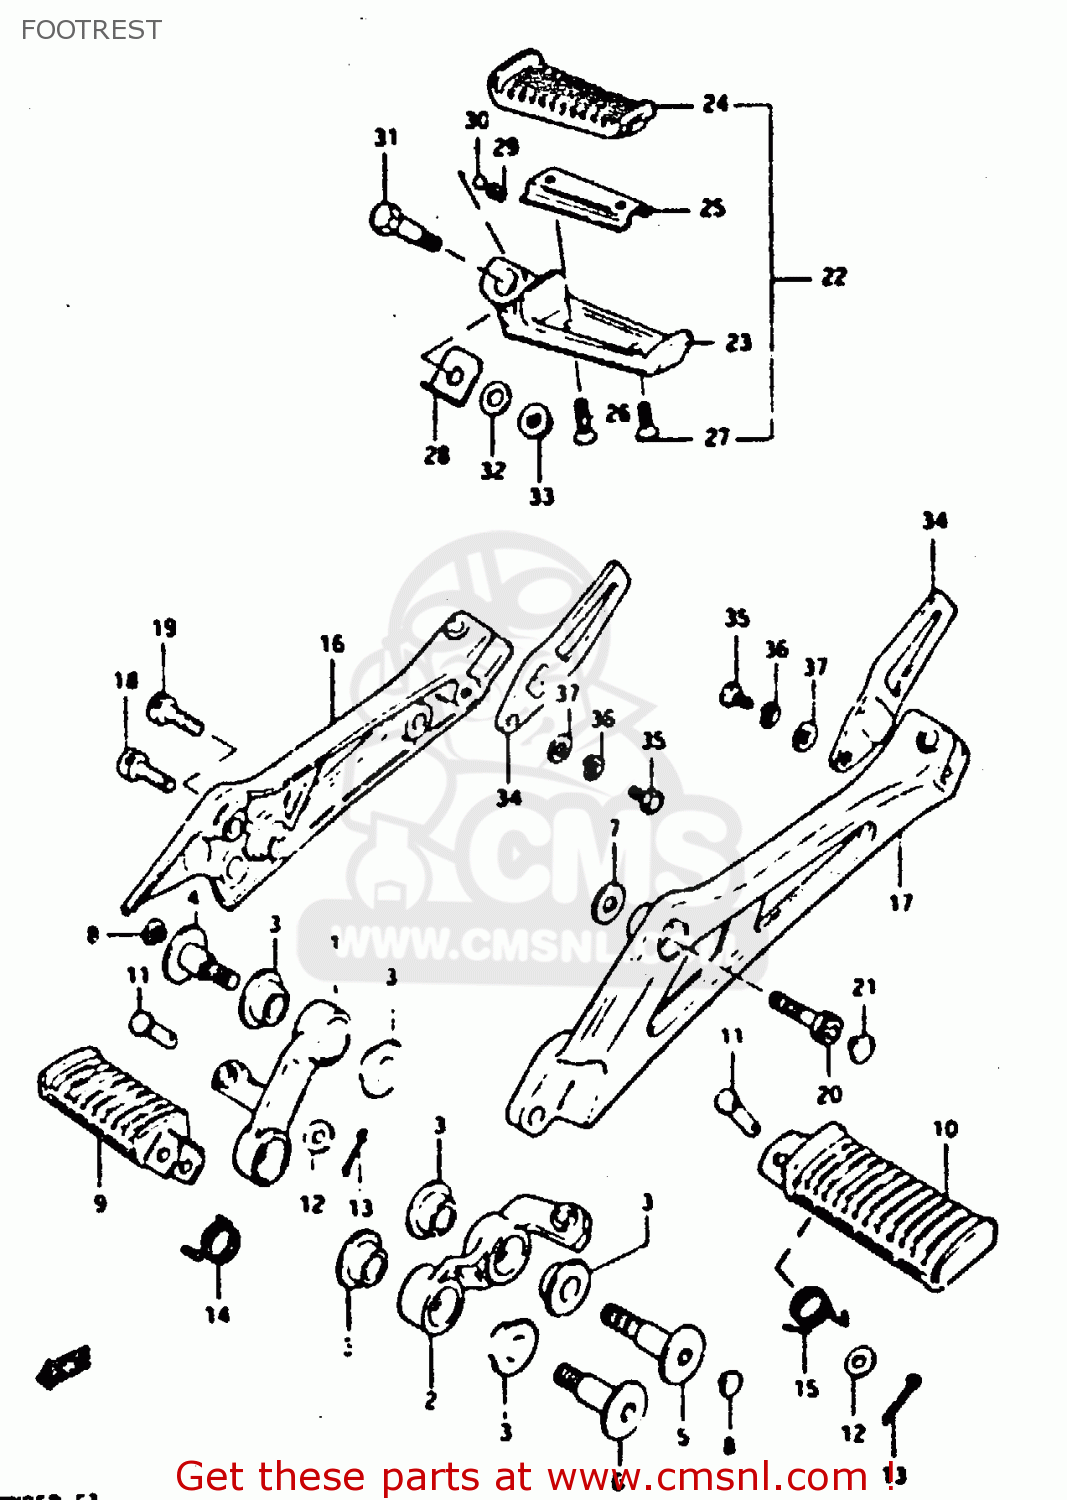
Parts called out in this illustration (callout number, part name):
1	BAR,FRONT FOOTREST,RIGHT
2	BAR,FRONT FOOTREST,LEFT
3	BUSH
4	BOLT
5	BOLT
6	BOLT
7	WASHER(10.5X28X2.3)
8	CAP
9	RUBBER,FR FOOTREST,R
10	RUBBER,FR FOOTREST,L
11	PIN
12	WASHER
13	PIN 20X20
14	SPRING
15	SPRING
16	BRACKET,MUFFLER,RIGHT
17	BRACKET,MUFFLER,LEFT
18	BOLT
19	BOLT
20	BOLT
21	CAP
22	FOOTREST ASSY,PILLION,R
23	BAR,PILLION FOOTREST,LEFT
24	RUBBER,PILLION FOOTREST
25	PLATE,RUBBER STOPPER
26	SCREW
27	SCREW 5X12
28	PLATE,SPRING STOP
29	SPRING
30	BALL
31	BOLT
32	WASHER 6MM
33	NUT
34	GUARD,REAR FOOT
35	BOLT
36	LOCK WASHER
37	WASHER
